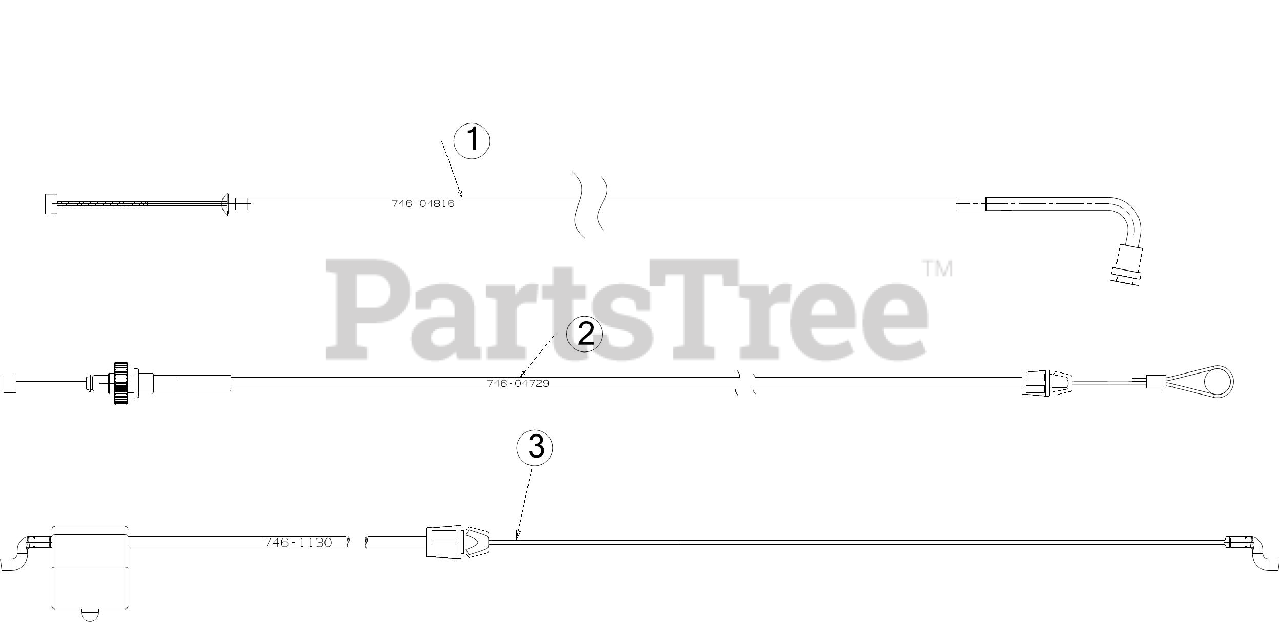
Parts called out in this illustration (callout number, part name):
1	SPEED SELECT CABLE W/ELBOW
2	SPEED ADJUSTMENT CABLE 56.25"
3	CONTROL CABLE
